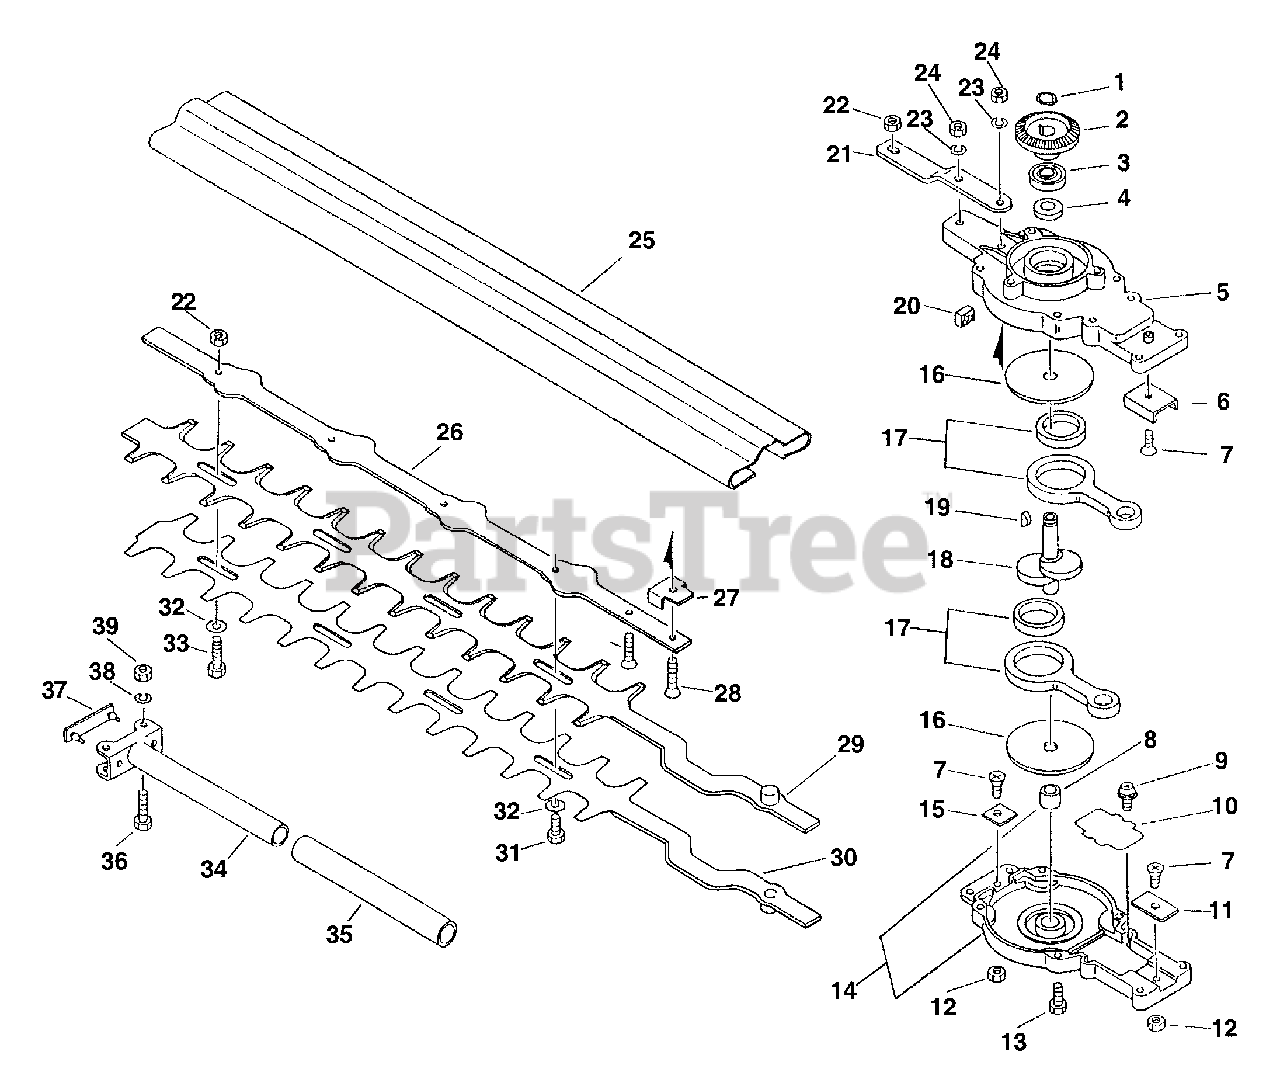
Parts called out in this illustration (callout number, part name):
1	RING, RETAINING - 10
2	GEAR - SPUR
3	BEARING, BALL - 6000
4	SEAL, OIL
5	CASE, GEAR
7	SCREW - 4X8
8	BEARING, PLAIN
9	SCREW - 3X6
10	PLATE, SIDE
13	BOLT - 5X20
14	GEAR CASE LID ASSY
15	PLATE, GUIDE
16	PLATE, SIDE
17	ROD, CONNECTING
20	SEAL, FELT
21	SUPPORT, BLADE
22	LOCKNUT - 6
23	LOCKWASHER - 5
25	COVER, BLADE
26	SUPPORT, BLADE
27	PLATE, ANGLE
28	SCREW - 5X20
29	BLADE - "TB" -- UPPER
30	BLADE - "BB" -- LOWER
31	BOLT - 6X22
32	WASHER - 6
35	GRIP, HANDLE
36	BOLT - 5X25
37	SEAL, FELT
38	LOCKWASHER - 5
